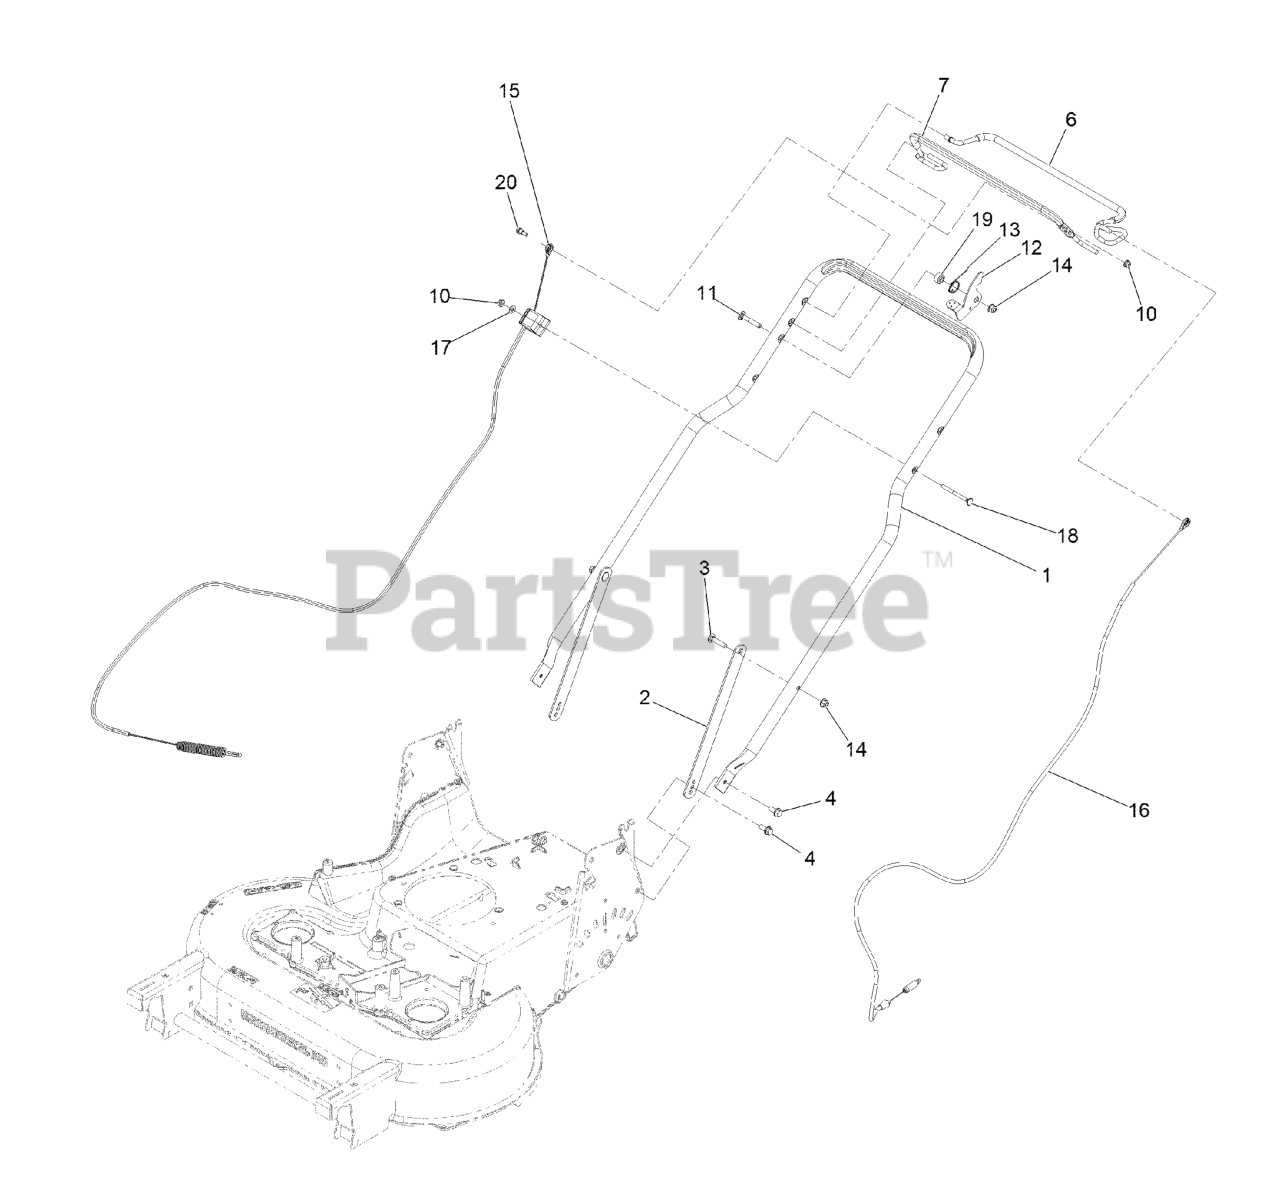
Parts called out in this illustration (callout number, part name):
2	SUPPORT-HANDLE
3	BOLT-CARR
4	SCREW-HHF
6	BAIL-TRACTION, COATED
7	BAIL-BBC, COATED
12	LEVER-BBC
13	SPRING-LEVER, BBC
14	NUT-HF, NI
15	CABLE-BBC
16	CABLE-TRACTION
17	Washer-Flat
18	SCREW-HANDLE
19	BUSHING-STEPPED
20	BOLT-SHOULDER
